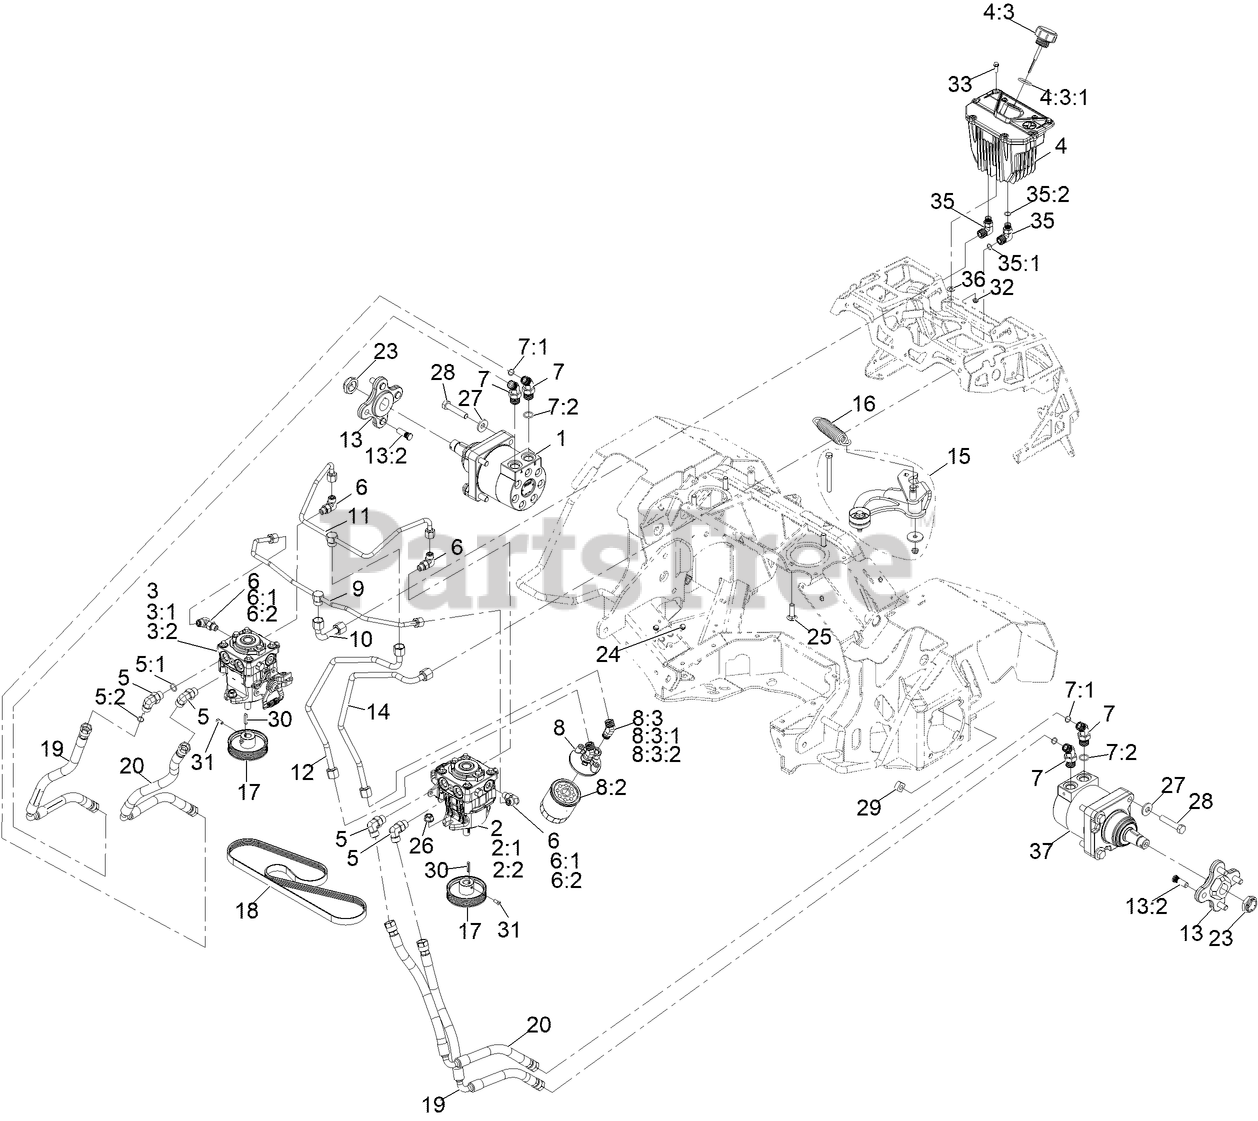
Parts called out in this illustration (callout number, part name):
1	MOTOR, TL195
2	PUMP, 12CC
2:1	KIT, 10CC/12CC PUMP KIT
2:2	SEAL OVERHAUL KIT
3	PUMP, 12CC
3:1	KIT, 10CC/12CC PUMP KIT
3:2	SEAL OVERHAUL KIT
4	ASM, HYDRAULIC RESERVOIR
4:3	Cap, Hydraulic
5	FITTING-ELBOW, 90 DEG
5:1	O-RING
5:2	O-RING
6	FITTING-ELBOW, 90 DEG
6:1	O-RING
6:2	O-RING
7	Fitting-HYD, 45 DEG
7:1	O-RING
7:2	O-RING
8	ASM, FILTER HEAD
8:2	FILTER-25 MICRON, BI-DIRECTIONAL
8:3	Adapter
8:3:1	O-RING
8:3:2	O-RING
9	LINE, HYDRAULIC, CASE TEE
10	LINE, HYDRAULIC, CASE
11	LINE, HYDRAULIC, CHARGE TEE
12	LINE, HYDRAULIC, CHARGE
13	ASM, HUB W/ STUDS
13:2	STUD-WHEEL
14	LINE, HYDRAULIC, SUPPLY
15	ASM, IDLER ARM
16	SPRING, EXTENSION
18	BELT, PVK5
19	KIT-STS HOSE- HYD
20	KIT-STS HOSE- HYD
23	LOCKNUT
24	SCREW-HWH
25	BOLT-CARR
26	NUT-HF, NI
27	WASHER-SPRING
28	SCREW-HH
29	NUT-SQUARE
30	KEY, 5MM X 5MM X 29MM
31	Screw-SQH
32	NUT-LOCK, NI
33	SCREW-HWH
35	Fitting-HYD, 90 DEG
35:1	O-RING
35:2	O-RING
36	Washer-Thrust
37	MOTOR, TL195
